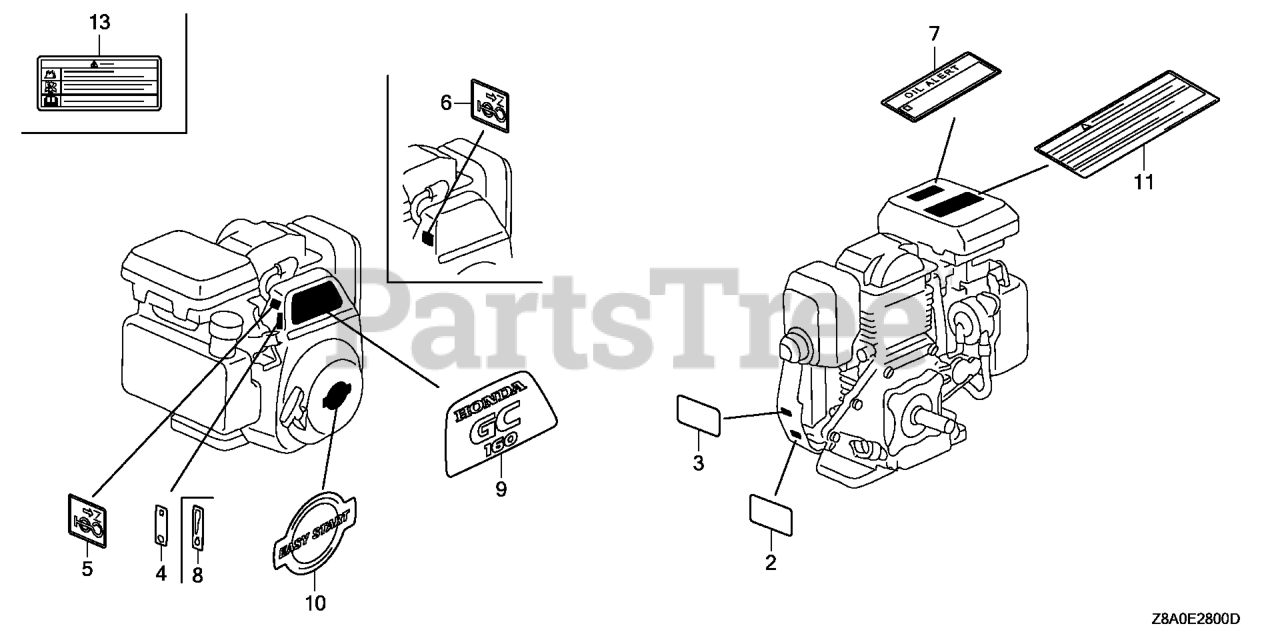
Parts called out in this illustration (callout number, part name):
2	LABEL, WARNING (NOT CERTIFIED FOR SALE)
4	MARK, ENGINE SWITCH INDICATION
5	MARK, CHOKE
7	MARK, OIL ALERT (ENGLISH)
9	EMBLEM (GC160)
10	MARK, RECOIL COVER
11	MARK, OPERATOR CAUTION (ENGLISH)
